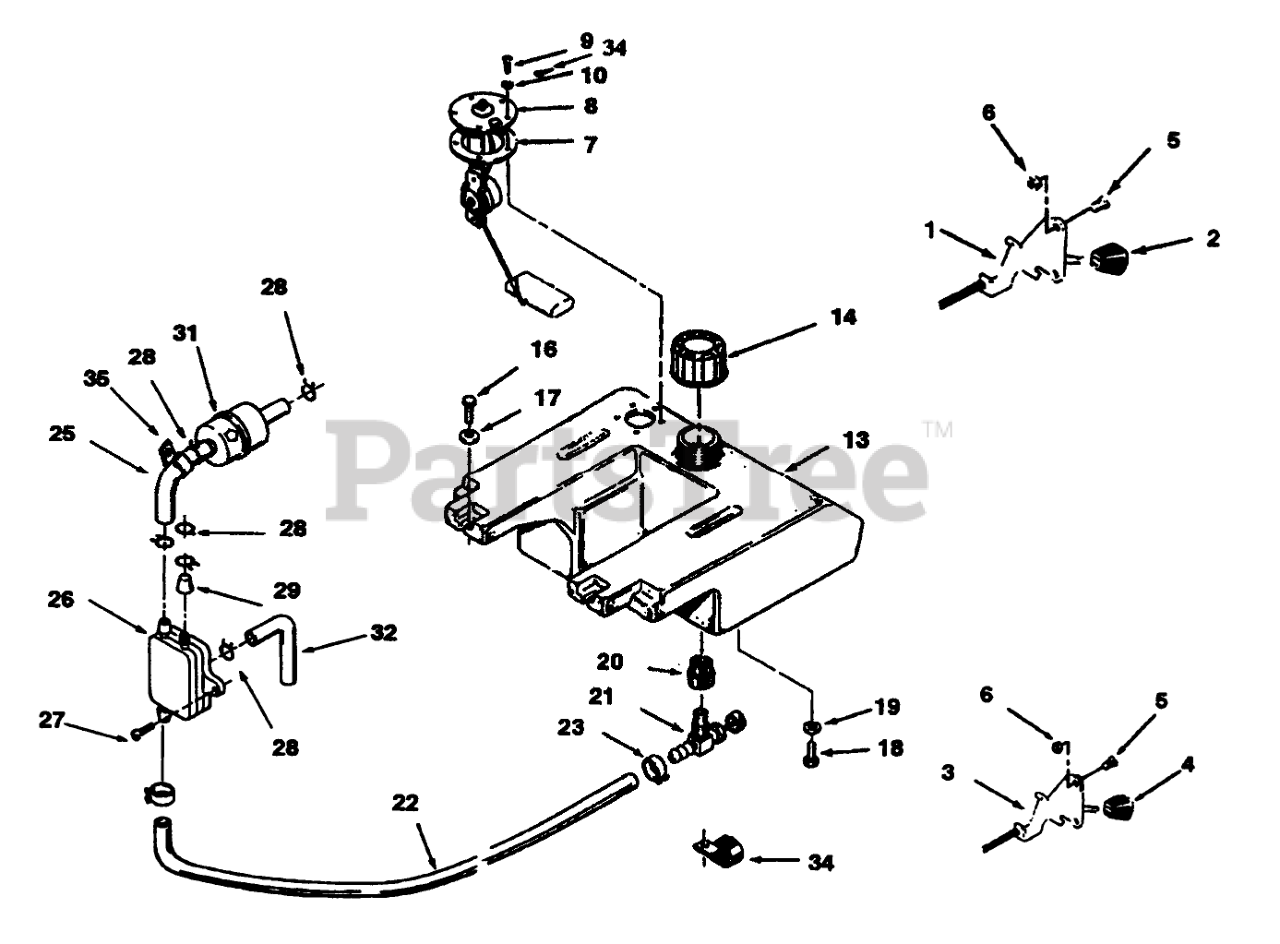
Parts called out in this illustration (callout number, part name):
1	CONTROL-THROTTLE
2	KNOB-CONTROL
3	CONTROL-CHOKE
4	KNOB-CONTROL
5	Screw
6	Nut
7	GASKET-SENDER, FUEL
8	SENDER-FUEL LEVEL
9	Screw
10	WASHER-LOCK
13	Tank-Fuel (Includes Items 20 & 21)
14	GAS CAP ASM
16	Bolt
17	WASHER-FLAT
18	SCREW-HH
19	WASHER-LOCK
20	BUSHING
21	VALVE-FUEL
22	FUEL HOSE 75" OF 6554
23	Clamp
24	Clamp
25	Hose
26	Fuel Pump
27	SCREW-TAPPING PAN HD
28	CLAMP-HOSE
29	Cap
30	Clamp
31	Filter-Fuel
32	Hose
34	TERMINAL-GROUND
35	Clip
